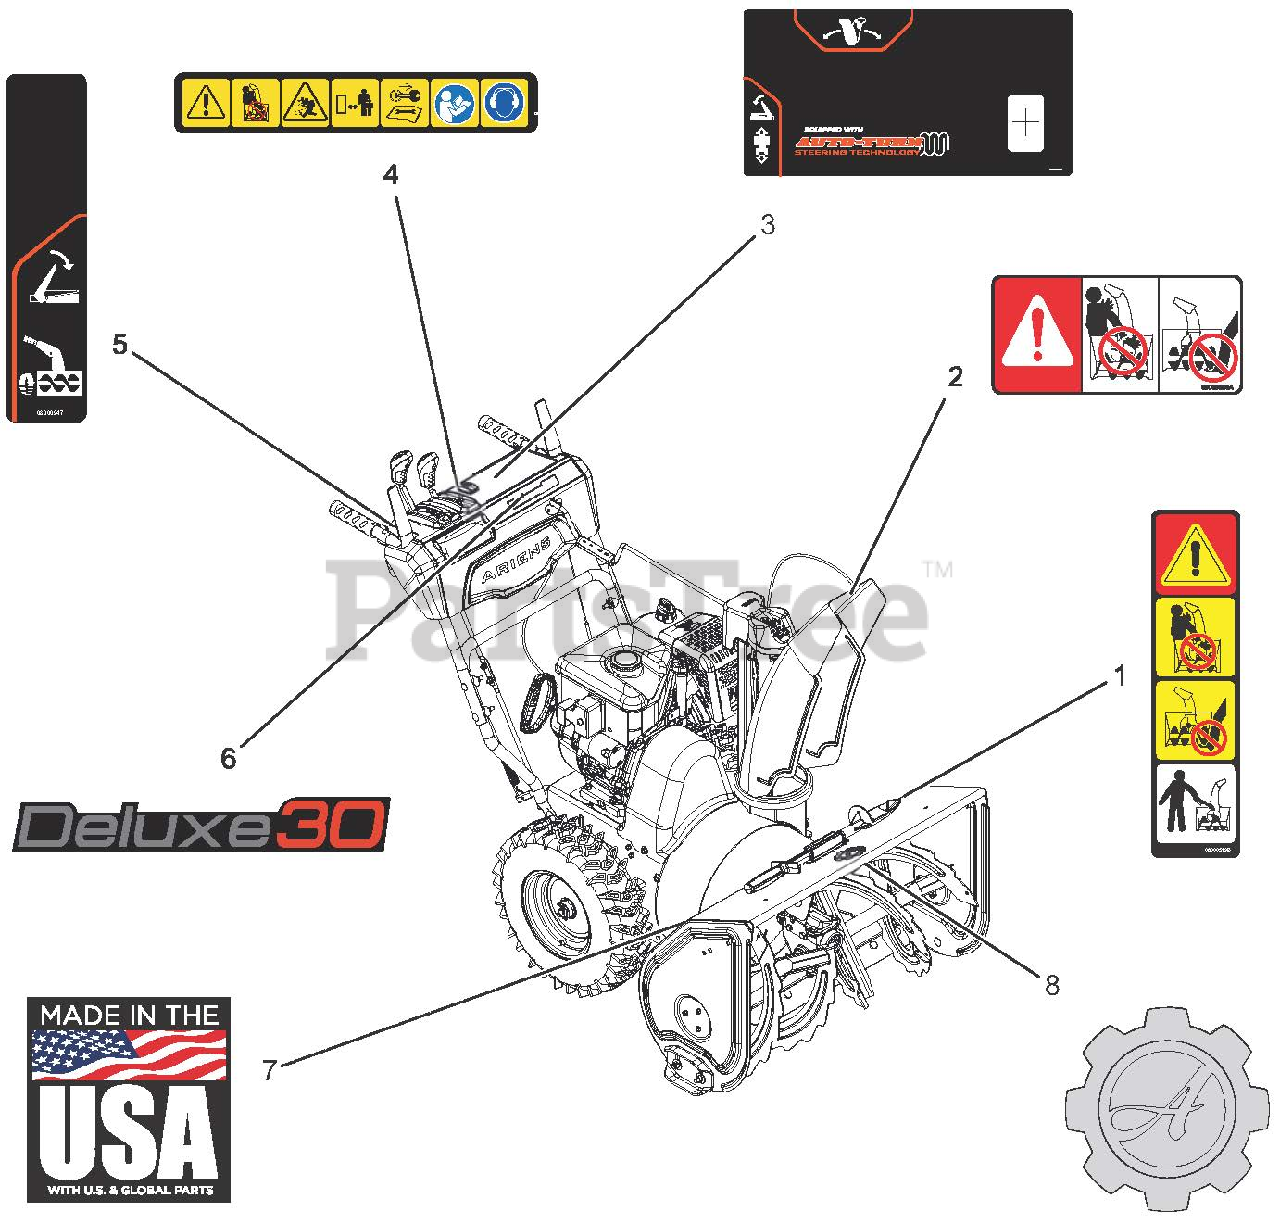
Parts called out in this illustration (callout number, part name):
1	DECAL, DANGER - ROTATING PARTS
2	DECAL, DANGER
3	DECAL,CONTROL-LG ID
4	DECAL,DASH - SAFETY
5	DECAL,CONTROL-RH CONTROL
6	DECAL, DASH - DELUXE 30
7	DECAL, MADE IN USA
8	DECAL, ARIENS-GEAR BADGE
